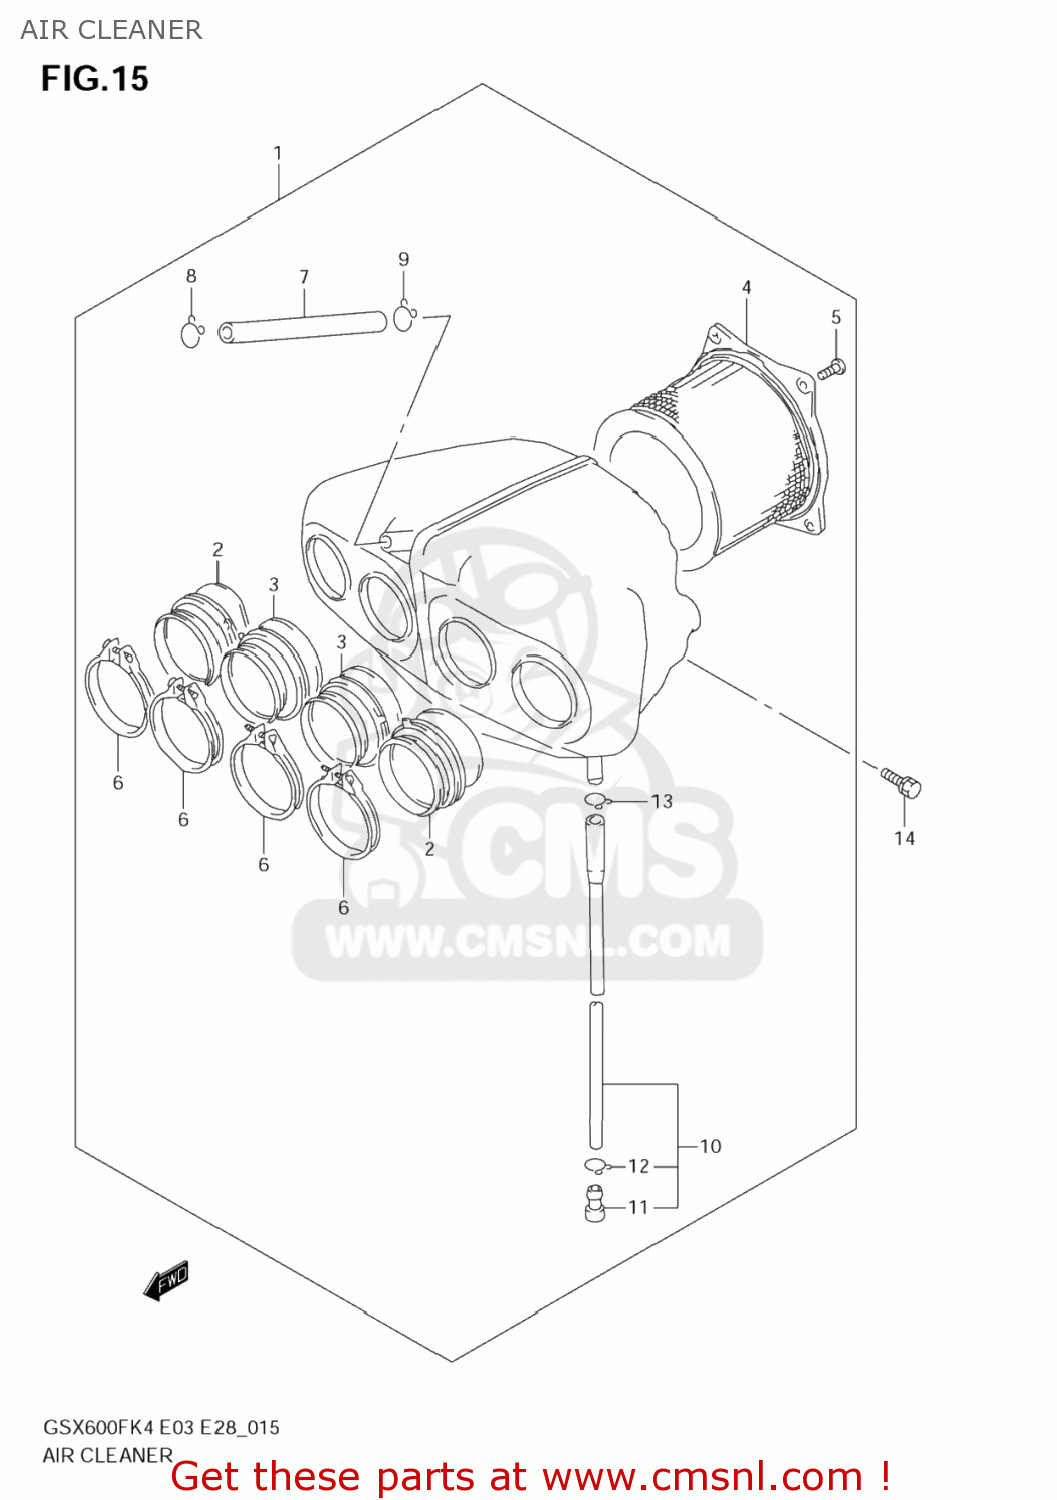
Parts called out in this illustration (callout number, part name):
1	CLEANER ASSY,AIR
2	TUBE,OUTLET,L/R
3	TUBE,OUTLET ML/MR
4	FILTER ASSY
5	SCREW 5X12
6	CLAMP
7	TUBE,BREATHER
8	CLIP
9	CLIP
10	TUBE,DRAIN
11	STOPPER,DRAIN
12	CLIP
13	CLIP
14	BOLT
